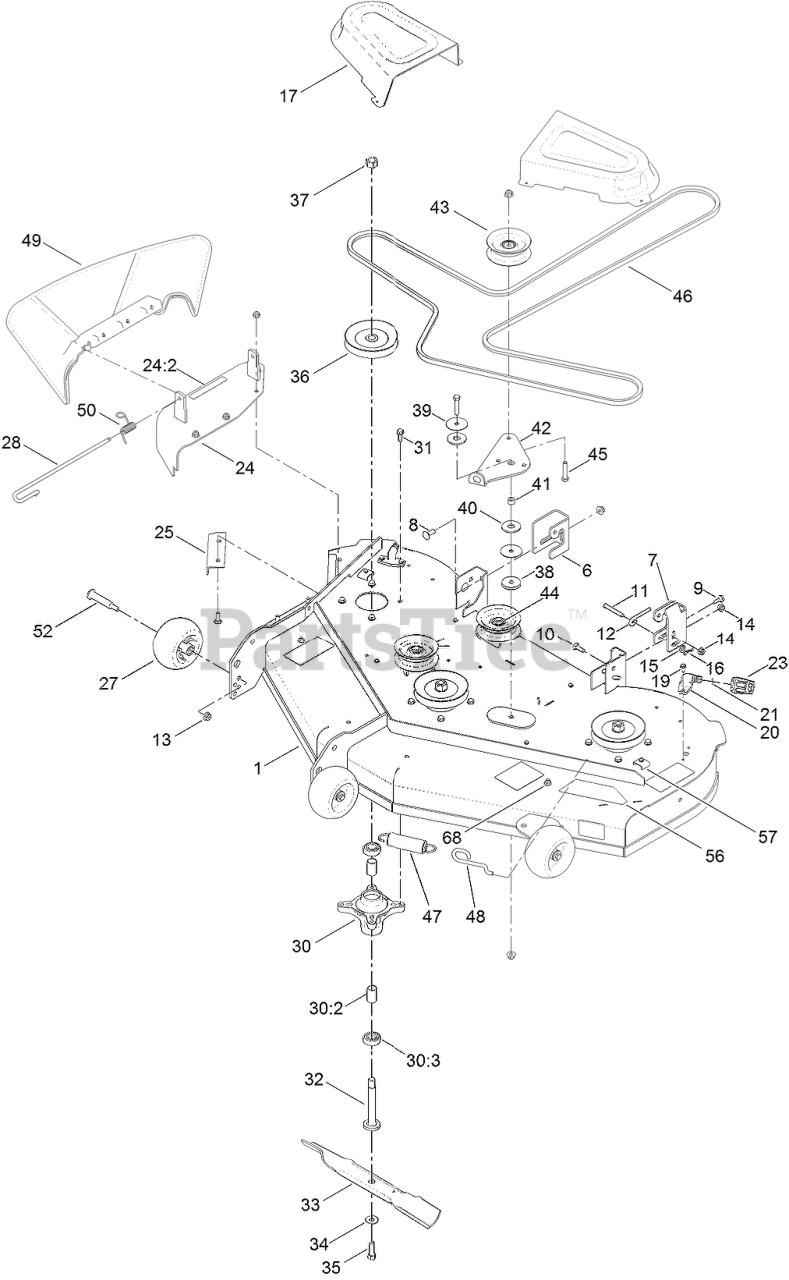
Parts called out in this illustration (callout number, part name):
1	DECK AND DECAL ASM
6	BRACKET-HANGER, RH
7	BRACKET-HANGER, LH
8	BOLT-CARR
9	SCREW-SHOULDER, HHF
10	SCREW-CARR
11	PIN-CLEVIS
12	ROD-LEVEL, DECK
13	NUT-HF, NI
14	NUT-HF, NI
15	WASHER-PLAIN
16	PIN-COTTER
17	COVER-BELT
19	SCREW-HWH
20	FITTING-WASHOUT
21	O-RING
23	CONNECTOR-HOSE
24	COVER ASM W/DECAL
24:2	DECAL-DANGER
25	BAFFLE-CUTOFF
27	ROLLER-SCALP, ANTI
28	PIN-CHUTE
30	SPINDLE ASM
30:2	SPACER
30:3	BEARING-BALL
31	SCREW-TAPTITE
32	SHAFT-SPINDLE
33	BLADE-HI LIFT
34	WASHER-BELLEVILLE
35	SCREW-HH
36	PULLEY
37	NUT-HEX
38	WASHER-PLAIN
39	WASHER
40	WASHER-FRICTION, COMPOSITE
41	SPACER
42	ARM-IDLER
43	PULLEY-IDLER, FLAT
44	WASHER-FLAT
45	SCREW-HH
46	V-BELT
47	SPRING-EXTENSION
48	HOOK-RETURN, SPRING
49	DEFLECTOR-DISCHARGE
50	SPRING-TORSION
52	BOLT-SHOULDER
56	DECAL-DECK
57	SCREW-TAPTITE
68	SCREW-HH
